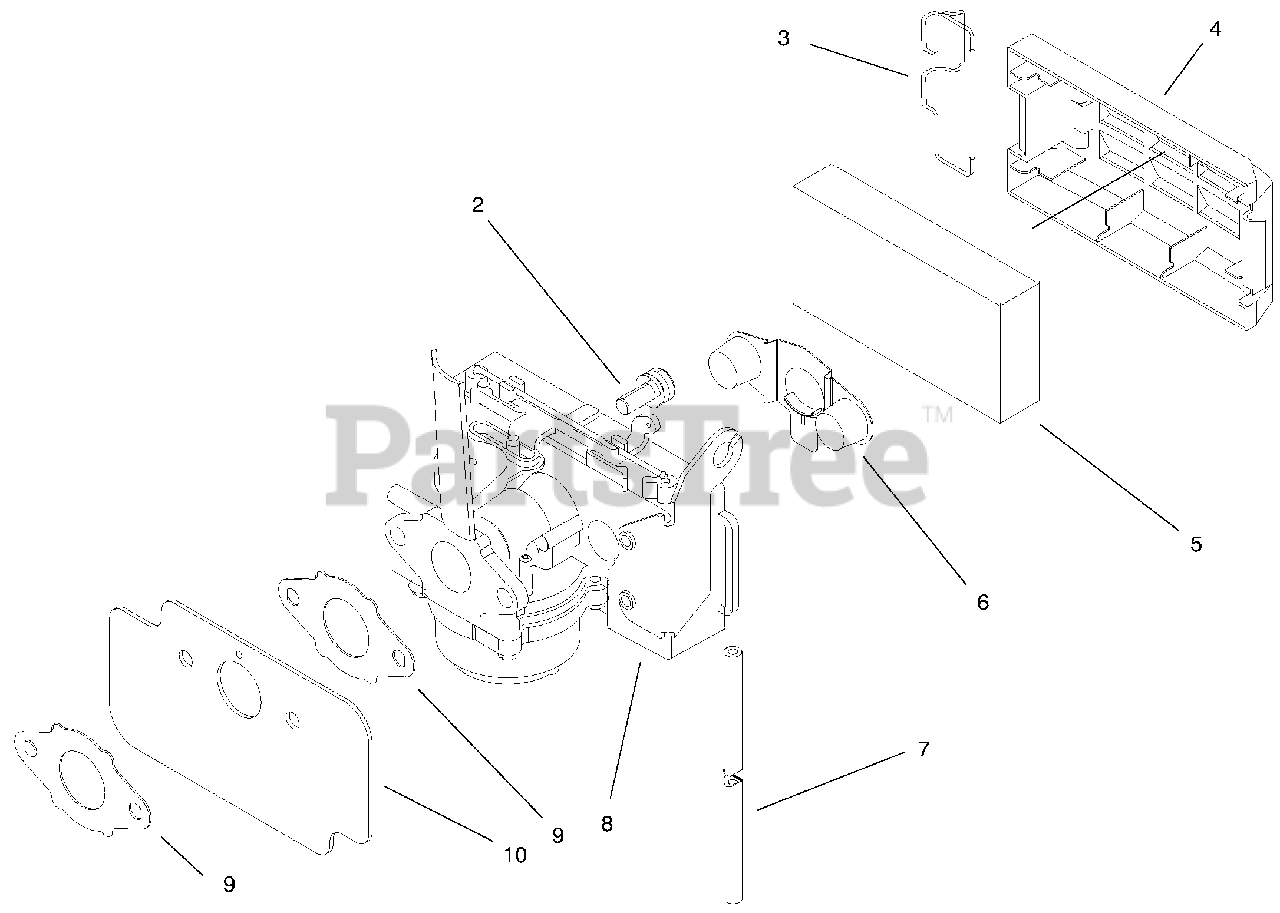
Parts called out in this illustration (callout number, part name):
3	Retainer-Filter
4	Cover-Air Cleaner
5	Element-Filter Air
6	Shield-Fuel
7	Hose-Primer
8	Carburetor Assembly (Incl. Ref. #9)
9	Gasket-Carburetor
10	Shield-Carburetor
